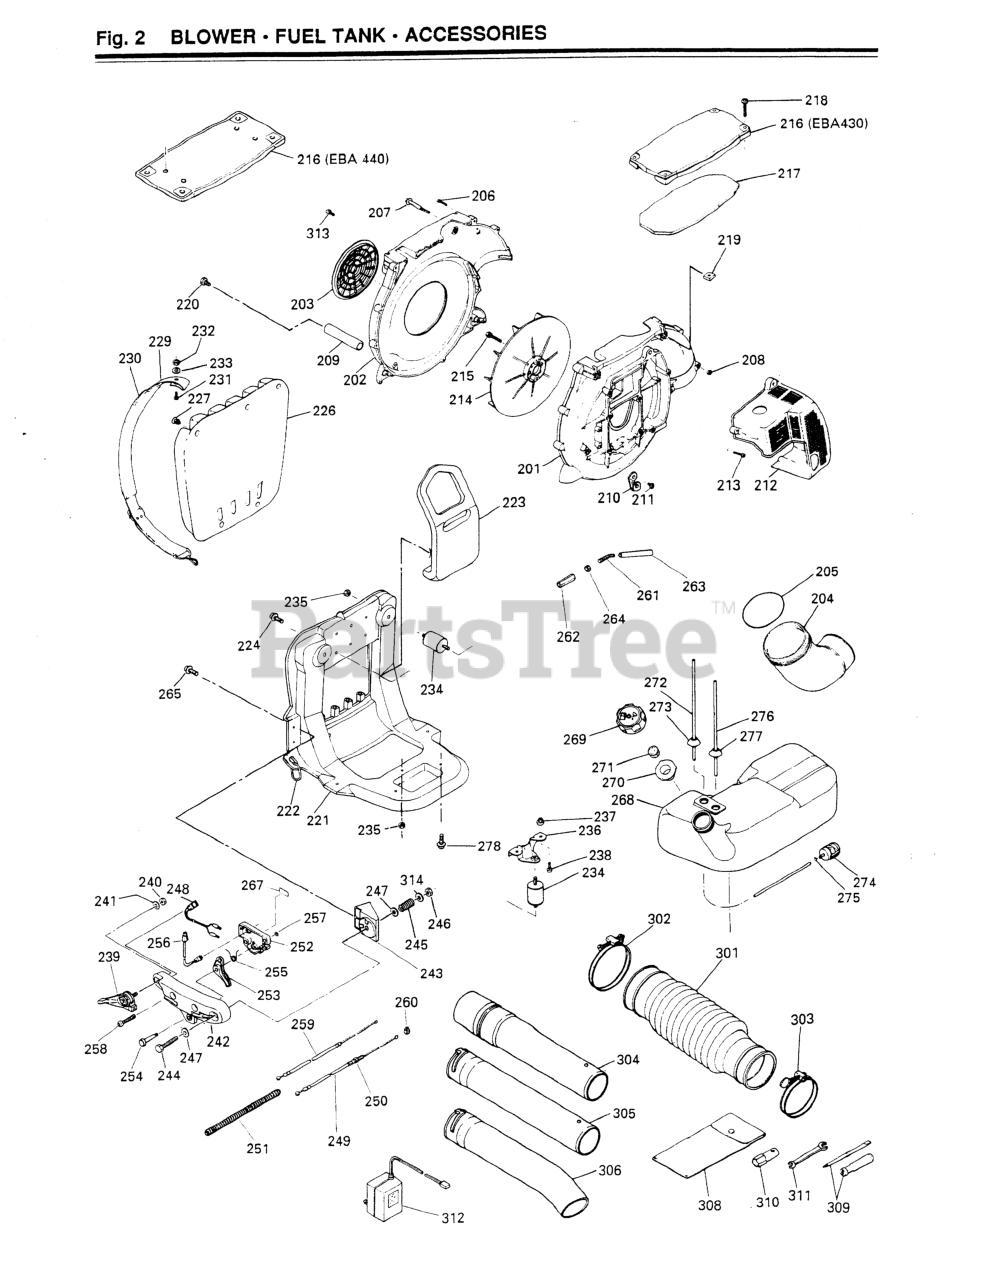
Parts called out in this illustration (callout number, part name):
205	O-RING
206	SCREW
208	NUT, M5 X 4
210	BRACKET
211	SCREW, M5 X 12
213	SCREW, M5 x 25
214	FAN (USE 3405-12102)
215	BOLT, M6x35 (RPLS -50635)
217	COVER, PACKING
218	SCREW
219	NUT
220	BOLT, M5 X 12
222	RING (USE -21121)
226	PAD (RPLS -21310)
227	CLIP (RPLS 3490-21320)
229	BAND
231	(NO LONGER AVAILABLE)
232	NUT, M6 X 5
235	NUT, M6 X 5
237	WASHER
238	SCREW, M5 x 16
239	LEVER, THROTTLE
240	NUT, M5 X 4
241	WASHER, M5x.8(RPLS 01624-20508
243	BRACKET
244	BOLT
245	SPRING
246	NUT, M6 X 5
247	WASHER, PLANE(USE 01640-20816)
248	SWITCH, STOP
249	CABLE COMP,THROTTLE EB441
250	NUT, M6 X 5
251	TUBE (USE 5548-73310)
253	LEVER
256	SWITCH ASSEMBLY
257	RING, SNAP, M4
258	SCREW
259	CABLE COMP, CHOKE
260	NUT, M6 X 5
261	PIPE (RPLS -83210)
263	TUBE (RPLS -83310)
264	NUT, M6 X 5
265	BOLT
267	LABEL, ARM
269	CAP ASSEMBLY (USE 3490-23203)
273	GROMMET
275	CLIP (REPLACES 2841-31280)
276	PIPE ASSEMBLY
277	GROMMET
301	HOSE, FLEXIBLE
302	2756-51510 (RPLS. 07280-09832)
304	JOINT, SWIVEL
305	PIPE, EXTENSION
306	PIPE, BENT
309	SCREWDRIVER
312	CHARGER, FOR 120V AC
313	SCREW, M5 X 10
314	WASHER
NI	LEVER (RPLS -25000)
